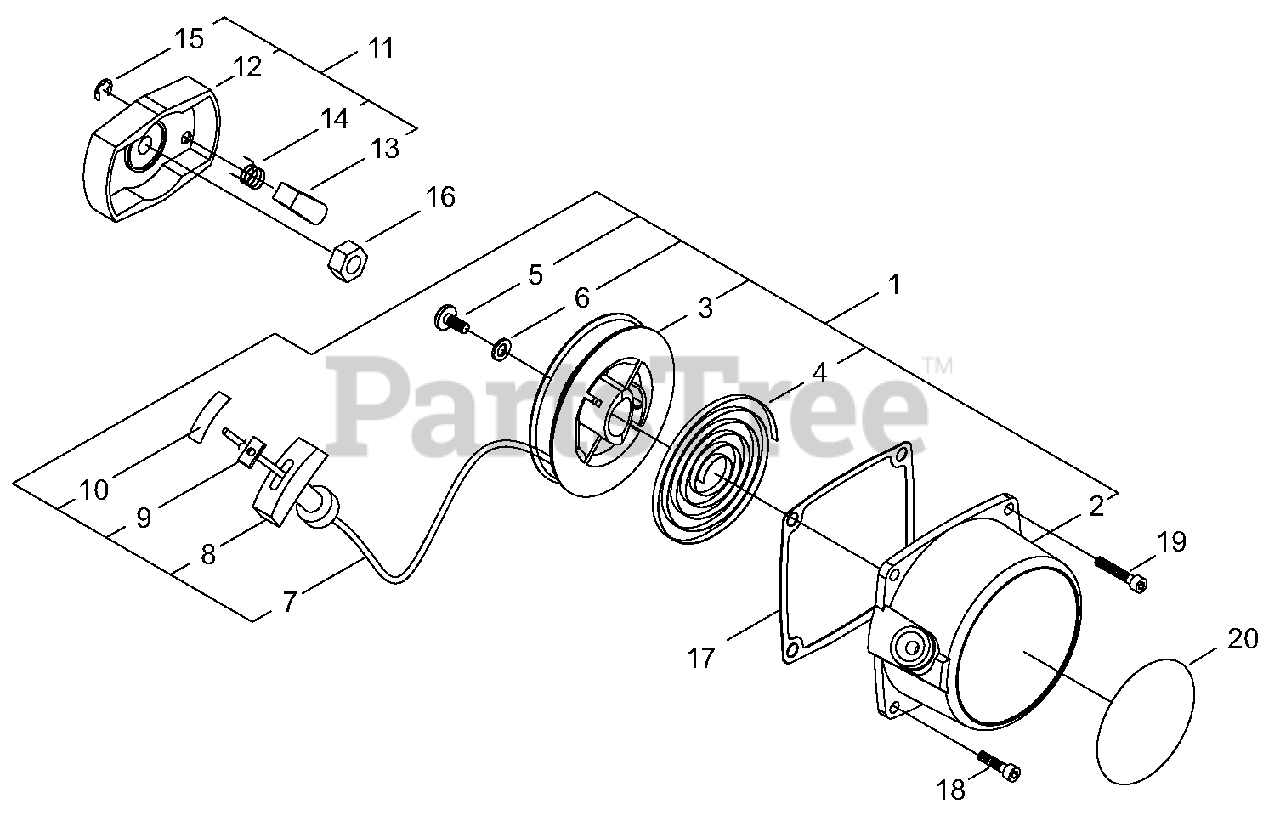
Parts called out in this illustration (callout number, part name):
1	STARTER ASSY
2	CASE, STARTER
3	REEL, ROPE
4	SPRING, REWIND
5	SCREW - 5
6	WASHER
7	ROPE, STARTER
8	GRIP, STARTER
9	RETAINER, ROPE
10	TAPE, ADHESIVE
11	STARTER PAWL ASSY
12	REEL, ROPE
13	PAWL, STARTER
14	SPRING, RETURN
15	RING, RETAINING
16	NUT - 8
17	GASKET, STARTER
18	SCREW - 4X16
19	SCREW - 4X20
20	LABEL - MODEL
